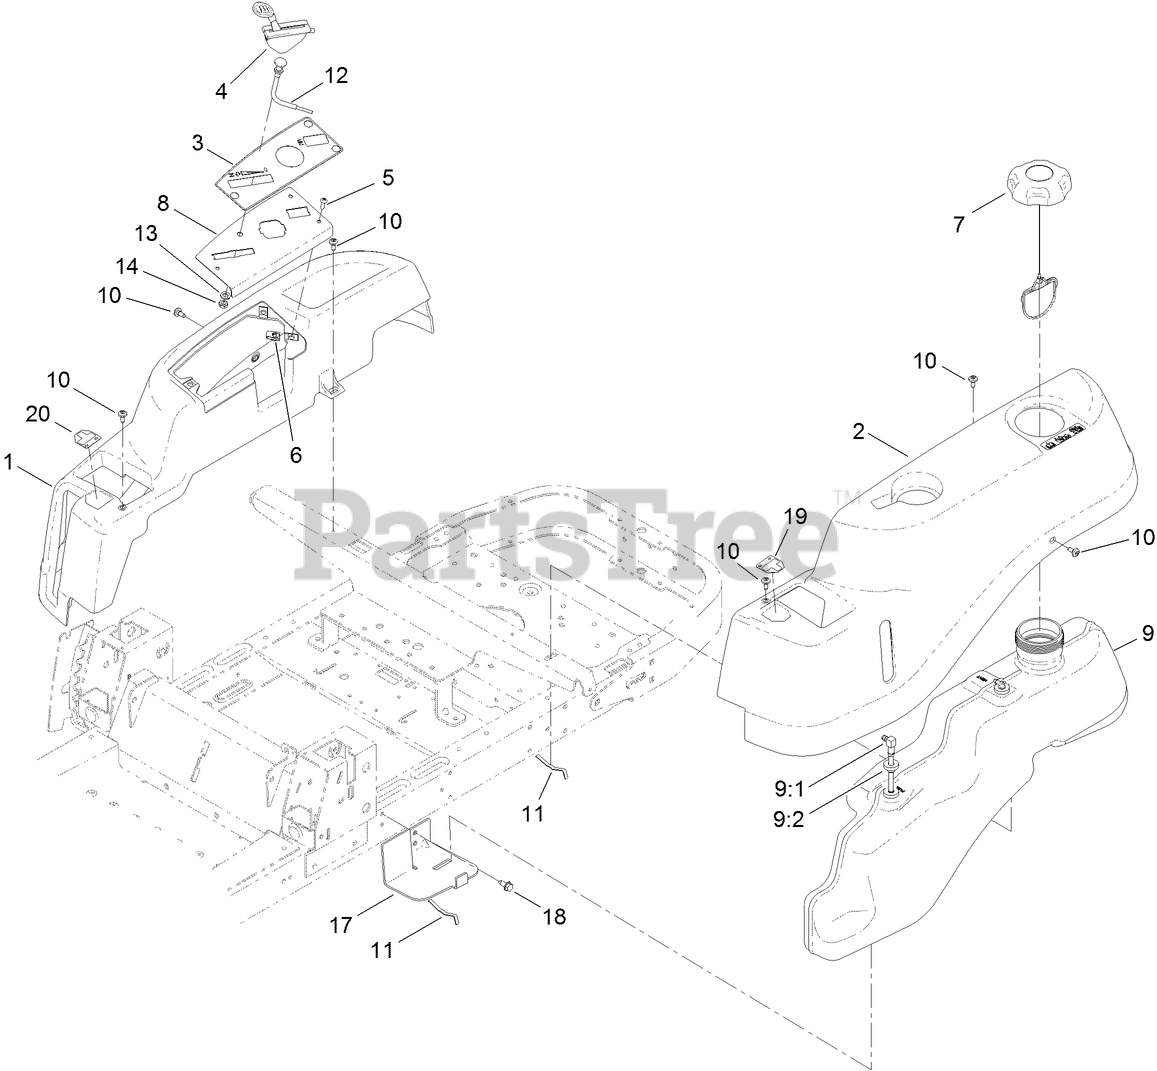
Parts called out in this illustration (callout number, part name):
1	POD-RH
3	DECAL-PANEL, CONTROL
4	CABLE-THROTTLE (45.0 IN)
5	SCREW-PRH
8	PLATE-CONTROL
9	FUEL TANK ASM
9:1	CONNECTOR-ELBOW, 90 DEG
9:2	BUSHING
10	SCREW-SHOULDER
11	SPRING
12	CABLE-CHOKE
13	WASHER-LOCK
14	NUT-HJ
17	SUPPORT-TANK, FRONT
18	SCREW-HWHTF
19	DECAL-LEVER, CONTROL (LH)
20	DECAL-LEVER, CONTROL (RH)
